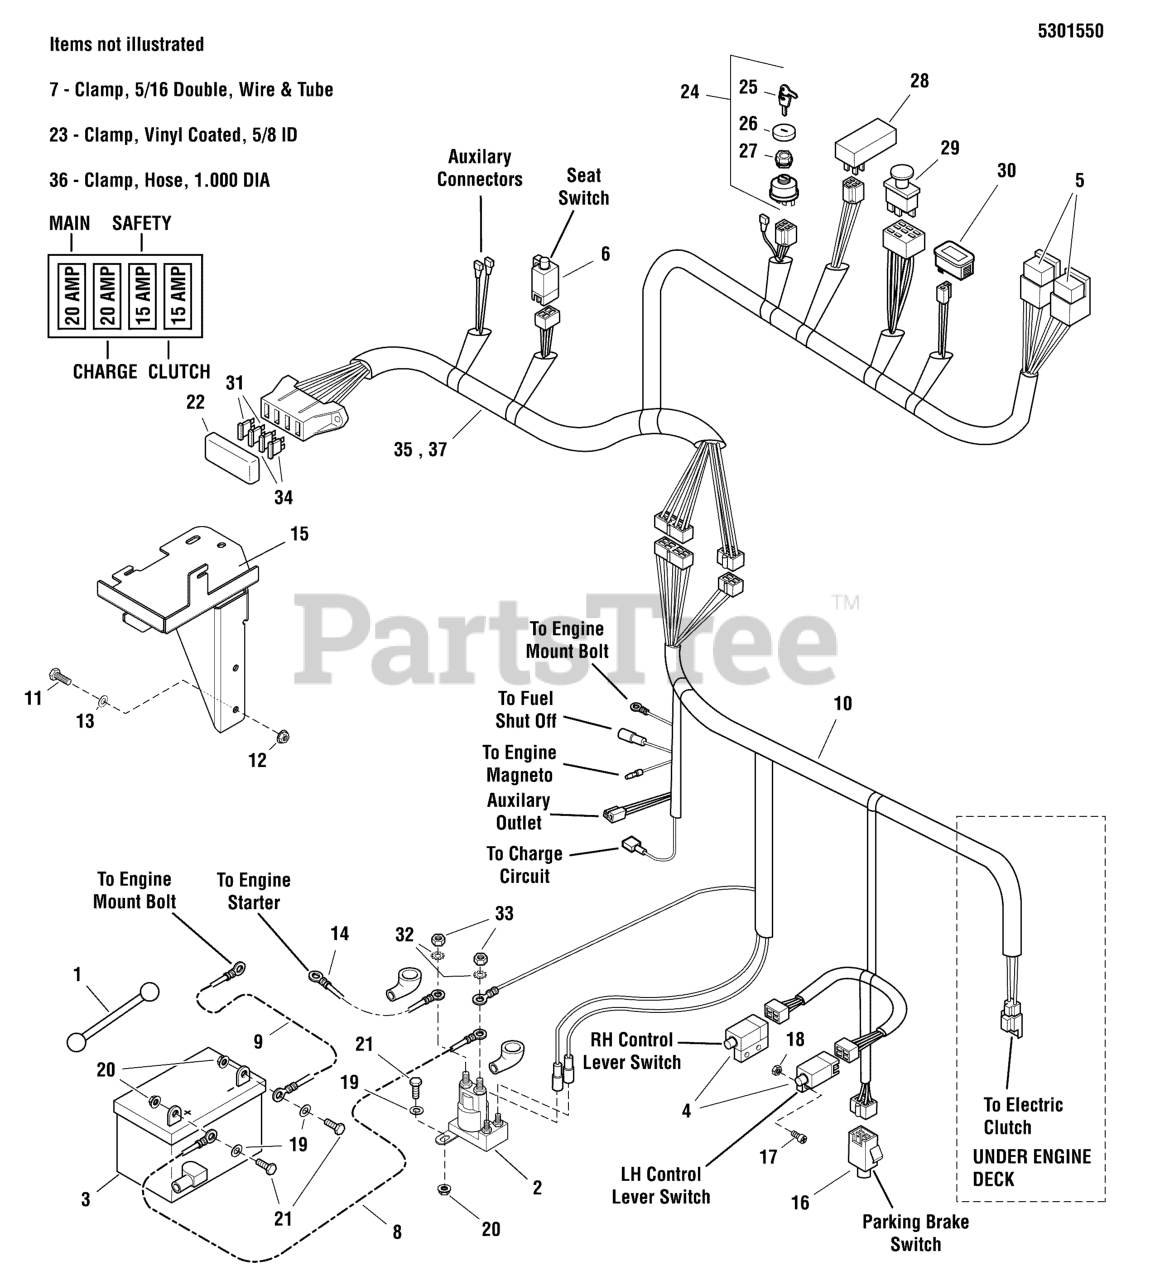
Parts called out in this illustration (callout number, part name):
1	STRAP-BLACK RUBB
2	SOLENOID-4 POLE 12 VOLT DC (TROMBETTA)
3	BATTERY, WET (BCIU1, 340 CCA)
4	SWITCH, PLUNGER, N.O.
5	RELAY, 12V, 40A
6	SWITCH, PLUNGER, NO/NO BOLT-ON
7	CLAMP, 5/16, DOUBLE, WIRE & TUBE
8	BATTERY CABLE, POSITIVE, 15
9	BATTERY CABLE, NEG, 22, 1/4-5/16
10	WIRE HARNESS, MAIN, EVO 36
11	BOLT, 3/8-16 X 1-1/2" GD5 CZ
12	NUT, 3/8-16 HEX NYLOCK FLANGE
13	WASHER, 3/8 SAE
14	BATTERY CABLE, POSITIVE, 22
15	WELD, BATTERY MOUNT - RED
16	SWITCH, DP NO/NC SNAP-IN
17	SCREW- #10-24 X 1/2 ROUND PHILLIPS
18	NUT, #10-24 HEX NYLON LOCK
19	WASHER, 1/4 SAE
20	NUT, 1/4-20 HEX NYLOCK FLANGE
21	BOLT, 1/4-20 X 3/4 GD5 YZ
24	SWITCH, IGNITION, 6 POST
25	KEY, IGNITION MOLDED SET
26	COVER, PLASTIC, SNAP ON
27	PLASTIC NUT
28	MODULE, TIME DELAY
29	SWITCH, BLADE ENGAGEMENT
30	HOUR METER
31	FUSE, ATO, 20 AMP
32	WASHER, LIGHT LOCK, 5/16
33	NUT, HEX JAM, 5/16-24
34	FUSE, ATO-15 (15 AMP)
35	WIRE HARNESS, OPERATOR COMPARTMENT, EVO
36	CLAMP, HOSE, 1.000 DIA
37	WIRE HARNESS, ALL CONDITION SHUT DOWN
